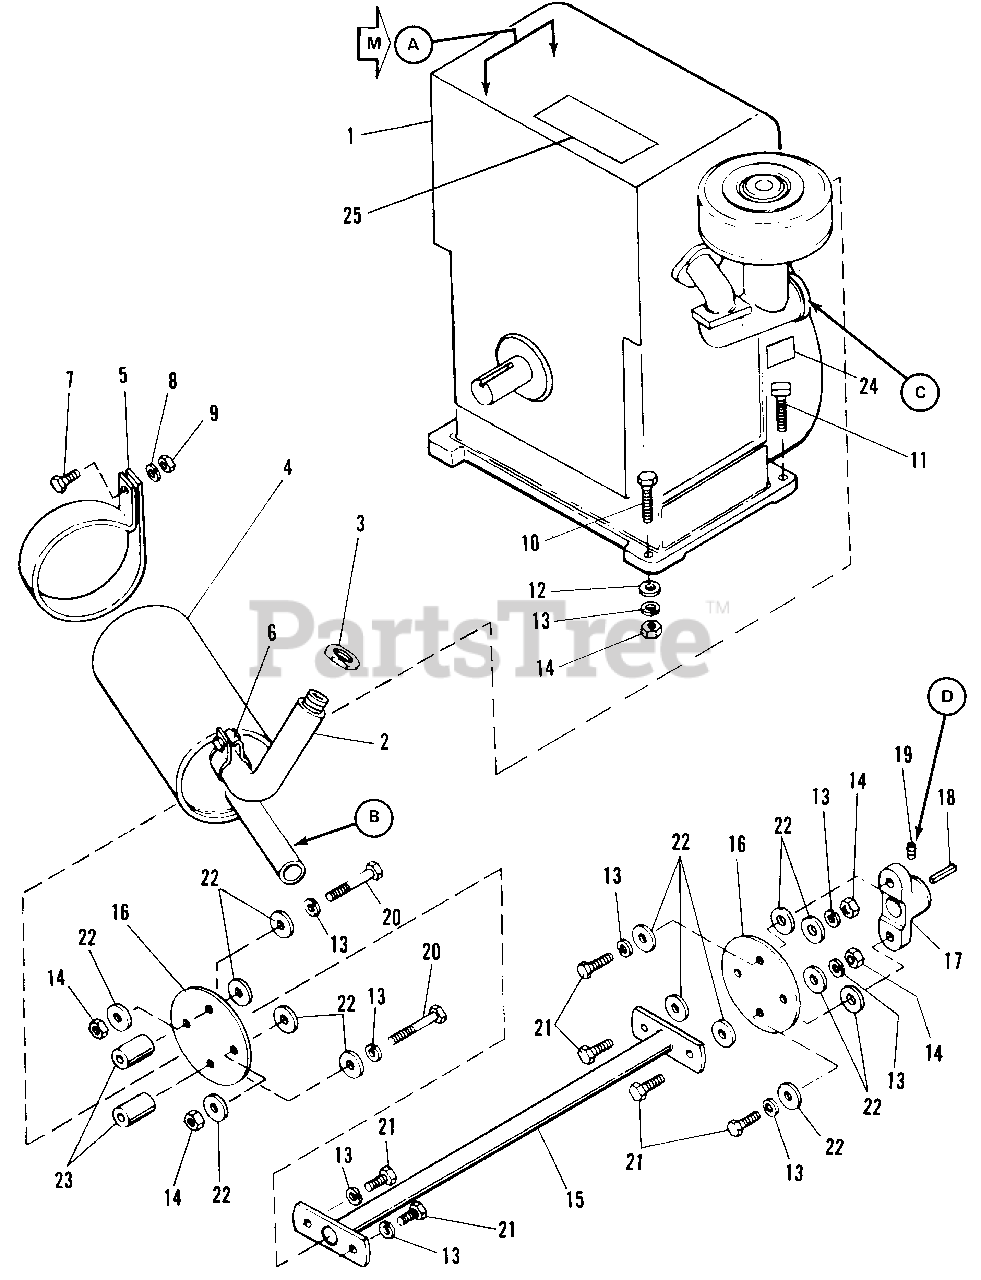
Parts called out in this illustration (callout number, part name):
1	ENGINE, 16 H.P.-Briggs & Stratton
2	ELBOW & NIPPLE ASSEMBLY
5	STRAP, Muffler
6	CLAMP, Muffler
7	CAPSCREW, Hex Hd., 5/16-18 x 1-1/2
8	DECAL, Safety
9	NUT, Hex, 5/16-18
10	CAPSCREW, Hex Hd., 3/8-16 x 1-1/2
11	CAPSCREW, Hex Hd., 3/8-16 x 1-5/16
12	WASHER, 3/8
13	LOCKWASHER, 3/8
14	NUT, Hex, 3/8-16
15	DRIVESHAFT ASSEMBLY
17	FLANGE, DRIVESHAFT
18	KEY, Driveshaft
19	SETSCREW, 3/8-24 x 3/8
20	CAPSCREW, Hex Hd., 3/8-16 x 2-1/4
21	CAPSCREW, Hex Hd., 3/8-16 x 1-1/4
22	WASHER, Special
24	DECAL, Oil Level
